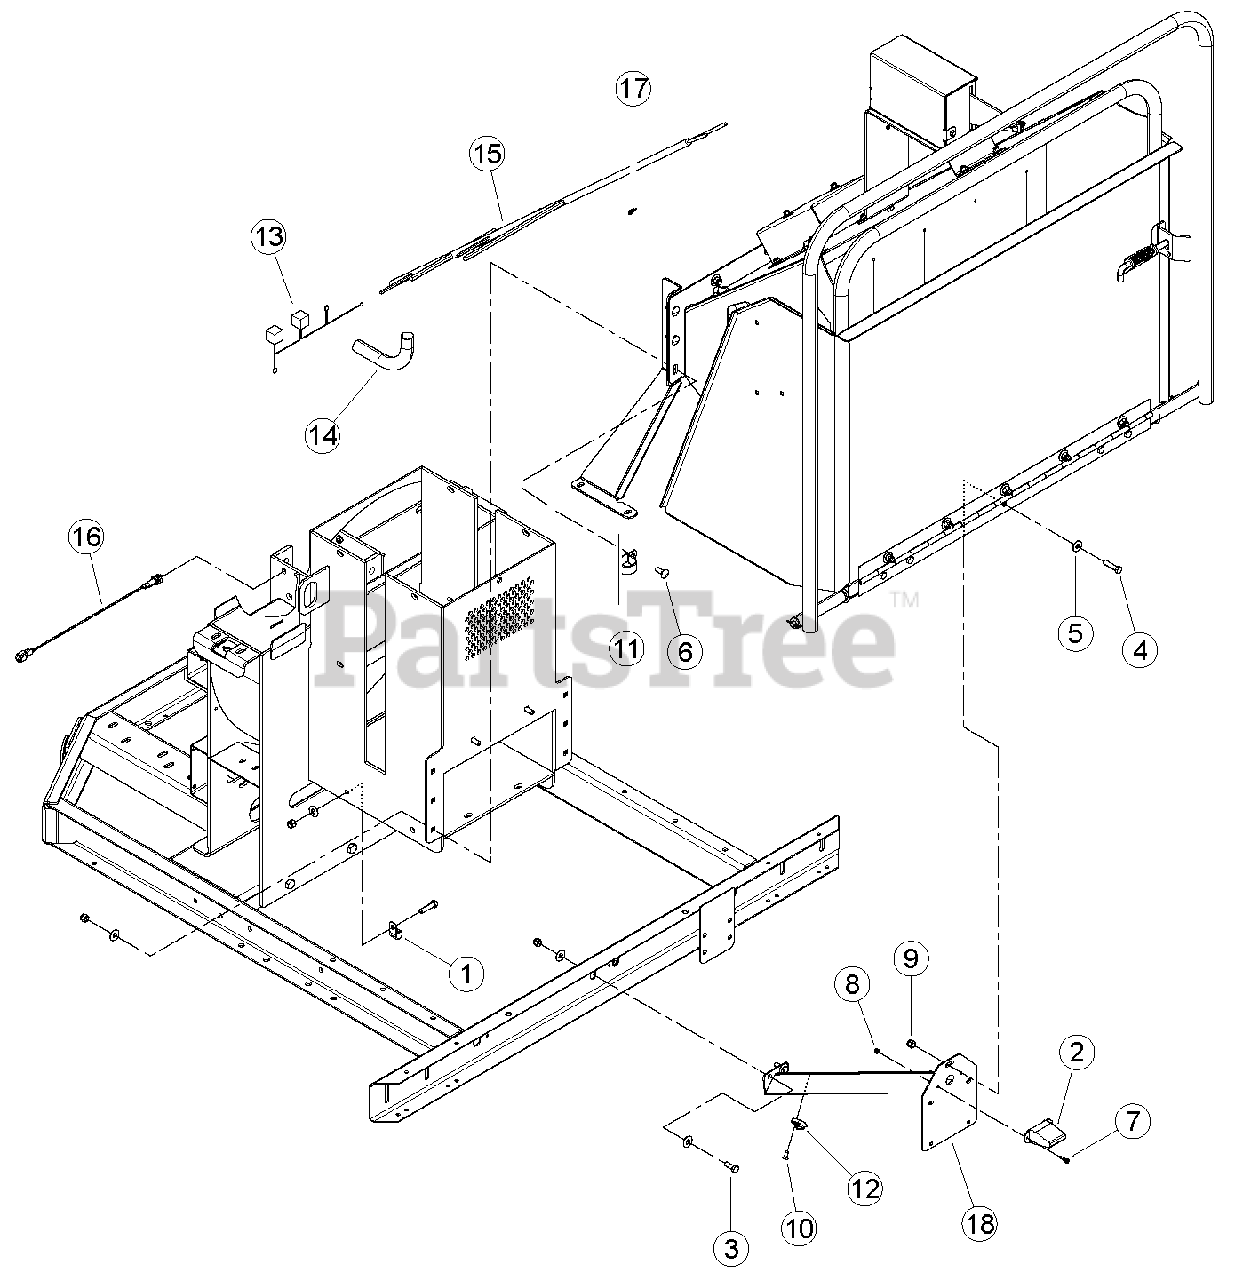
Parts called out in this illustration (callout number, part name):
1	CLAMP, 9/16 COATED
2	LIGHT, LICNESE PLATE
3	BOLT, 3/8 NC X 1 HEX HD GR5 ZP
4	BOLT, 3/8 NC X 1-1/2 HEX HD
5	WASHER, 3/8 FLAT ZP
6	BOLT, 3/8 X 1 CRG
7	SCREW, #10 X 3/4 HEX TAP SC
8	NUT, 8-32 NYLOCK
9	NUT, 3/8 NE NYLOCK ZP
10	RIVET, AL BLIND 1/4 X 3/4 DOME HEAD
11	CLAMP, 1-9/16 COATED
12	CLAMP, CABLE MOUNT
13	HARNESS, CHIPPER SAFETY RELAY
14	SLEEVING, BRAIDED ELECTRICAL HARNESS
15	HARNESS, 6" GAS PLUS 1 CONTROLLER
16	SENSOR, M12 PNP PROXIMITY
17	PLUG, JUMPER HARNESS
18	WELDMENT, CHUTE SUPPORT
